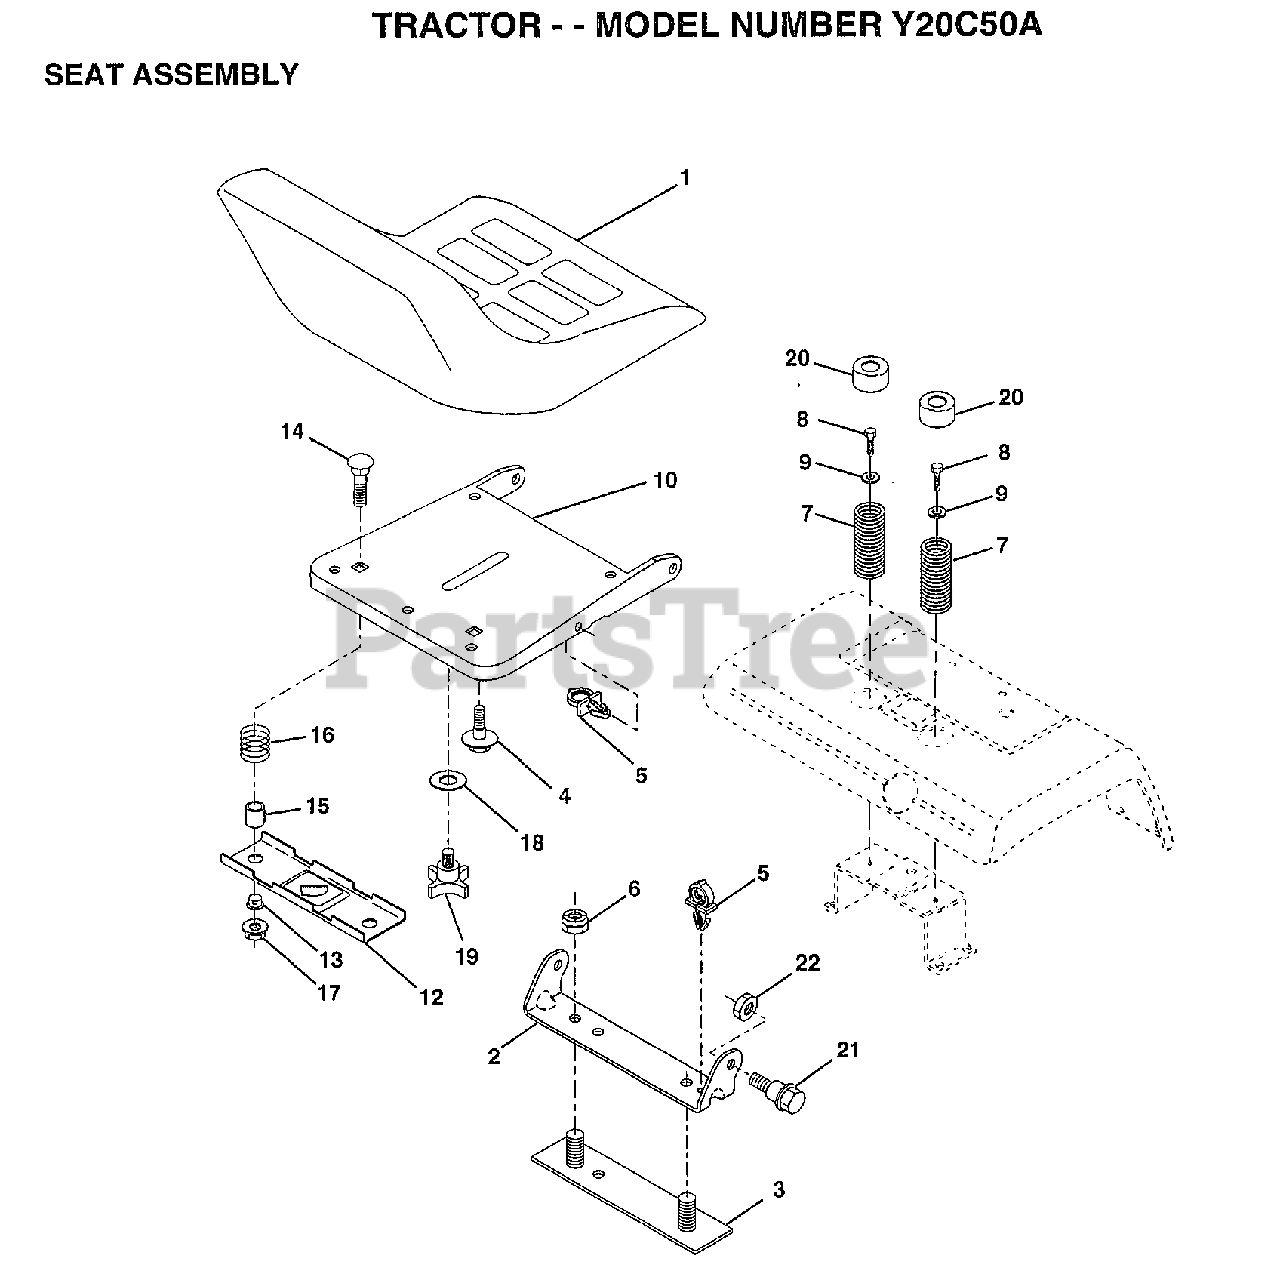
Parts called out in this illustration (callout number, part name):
2	BRACKET PVT SEAT
3	STRAP ASM FENDER
4	"BOLT,SHOULDER"
5	CLIP.PUSH-IN.HING
7	SPRING COMPRESSIO
8	SCREW LT
9	WASHER
12	BRKT SWITCH
13	BUSHING
15	SPACER SPLIT
16	SPRING COMPRESSED
18	WASHER
19	"KNOB 1/2"" YT"
20	CAP SPRING
21	BOLT.SHLD.5/16-18
